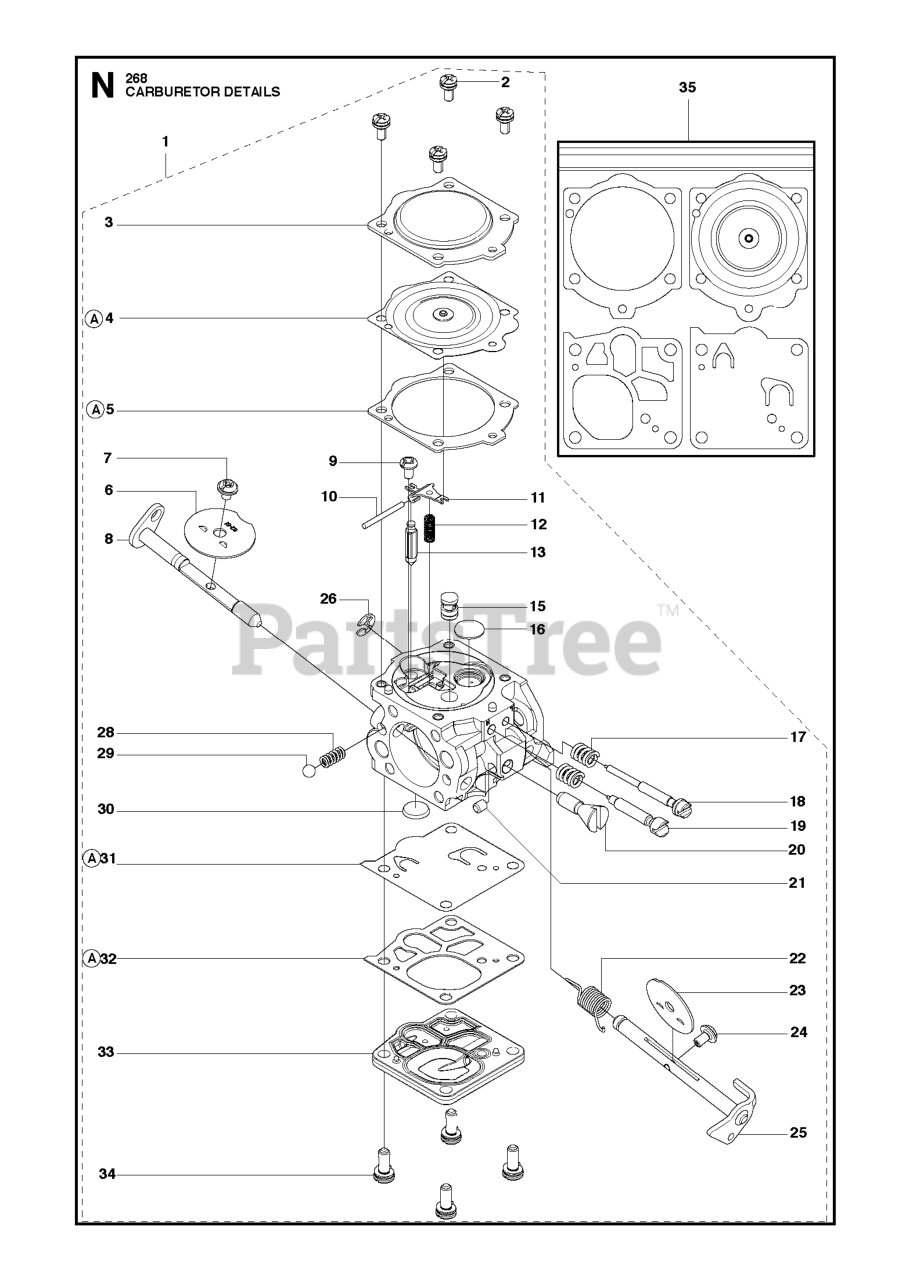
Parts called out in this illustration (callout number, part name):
1	CARBURETOR
2	RP SCREW W/ WASHER
3	DIAPHRAM COVER
4	DIAPHRAGM ASSY
6	CHOKE FLAP
7	SCREW
12	SPRING-METER.LEVER
13	VALVE/INLET.
16	WELCH PLUG
17	SPRING/COMPRESSION
18	NEEDLE-LO ADJ
21	PLUG FRICTION
30	FUEL INLET SCREEN
31	DIAPHRAM PUMP
34	SCREW W/ WASHER
35	GASKET KIT
